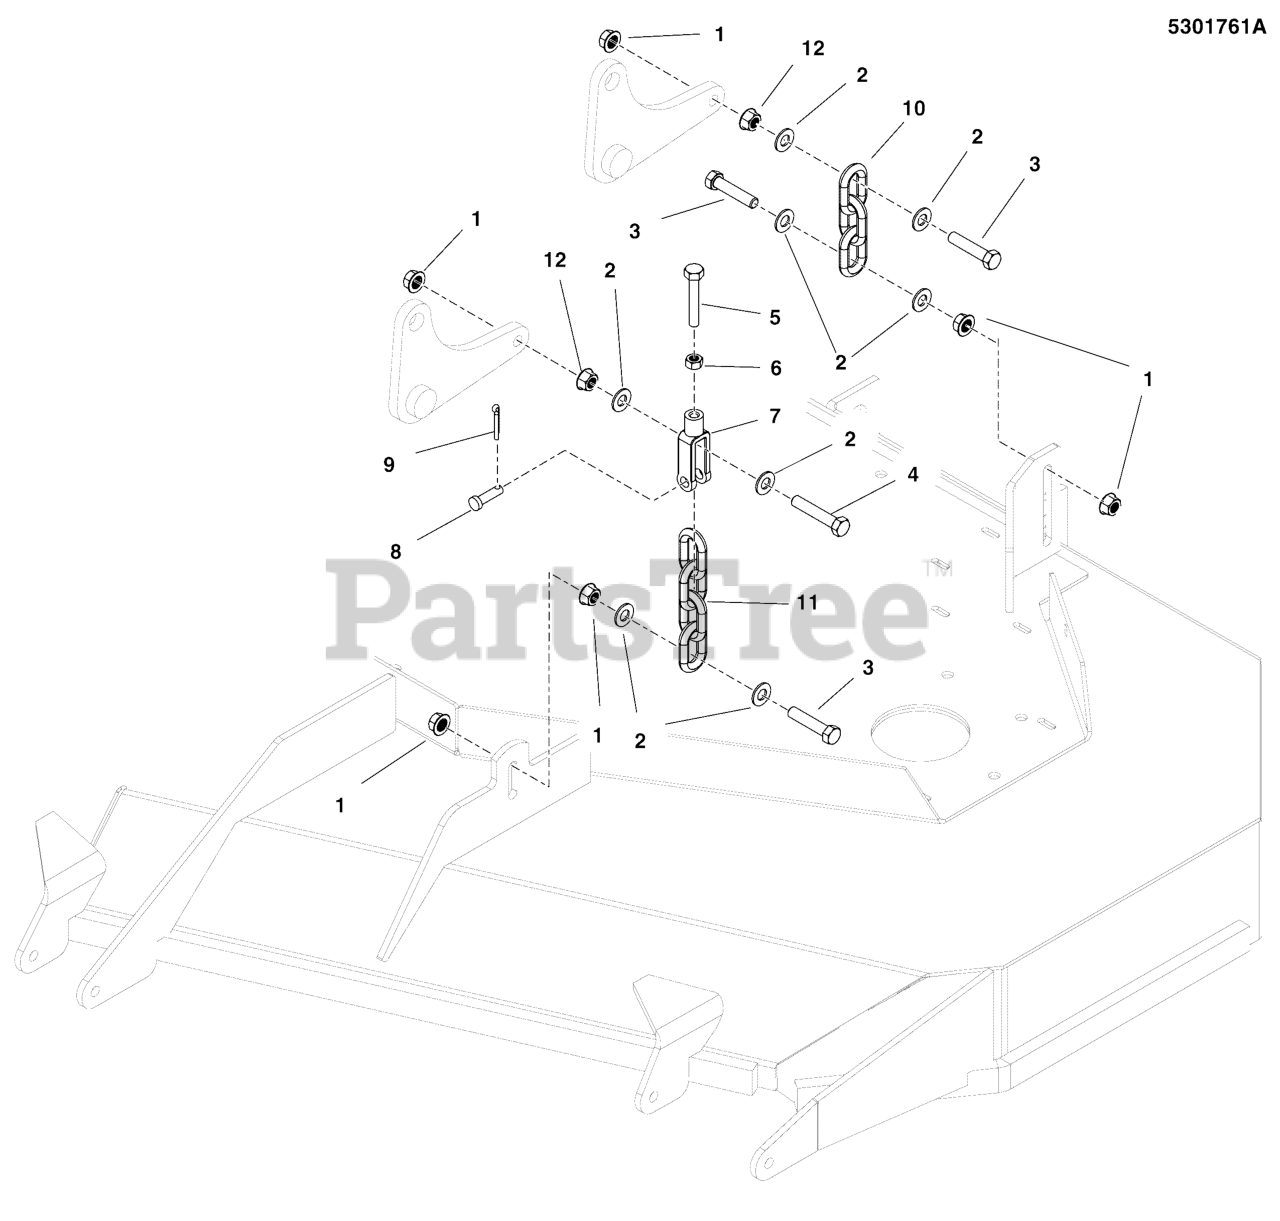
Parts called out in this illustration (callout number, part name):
1	NUT, 3/8-16 HEX JAM
2	WASHER, 3/8 SAE
3	BOLT, 3/8-16 X 1-3/4" GD5 CZ
4	BOLT, 3/8-16 X 2, GD5, CZ
5	BOLT, 5/16-18 X 2 GD5 TFL
6	NUT, 5/16-18 HEX
7	CLEVIS, 5/16-18, 3/8 PIN HOLE, CLR ZINC
8	PIN, CLEVIS, 3/8 X 1-1/8, PLATED
9	PIN, 3/32 X .750, COT, ZINC/CLEAR
10	CHAIN, 5/16 GD30, 3 LINKS
11	CHAIN, 5/16" GD30, 4 LINKS
12	NUT, 3/8-16 HEX SERRATED FLANGE
